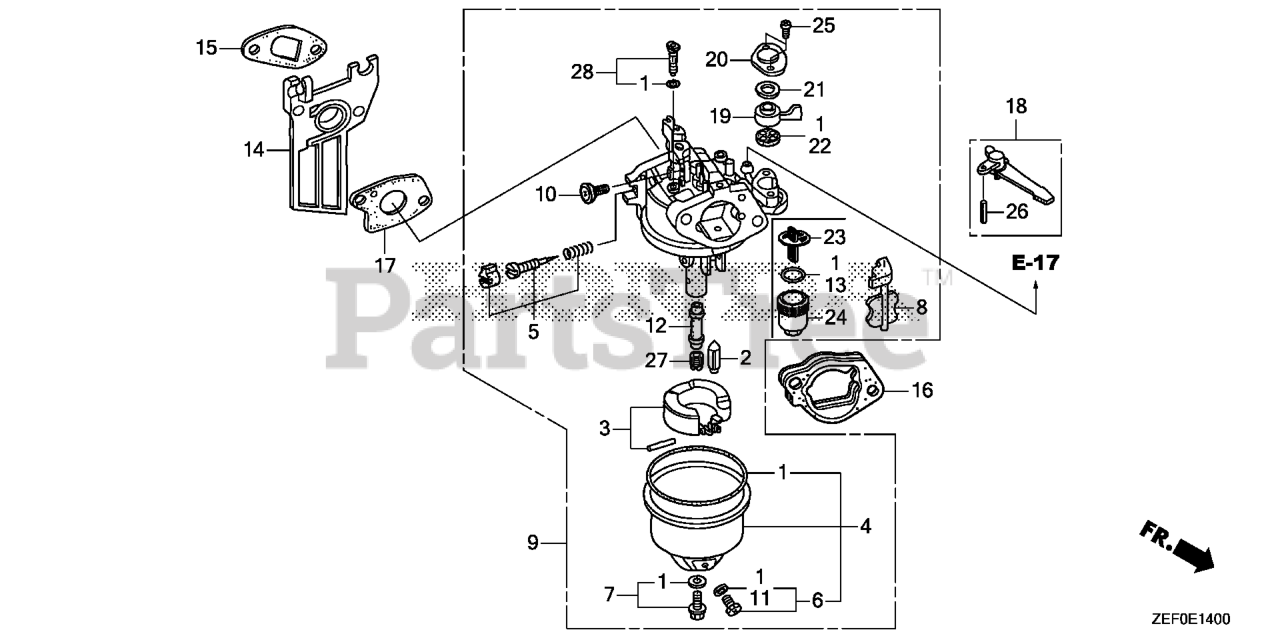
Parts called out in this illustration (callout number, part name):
1	GASKET SET
2	VALVE SET, FLOAT (CARBURETOR NO.) (SEAT NOT INCLUDED)
3	FLOAT SET
4	CHAMBER SET, FLOAT
5	SCREW SET (CARBURETOR NO.)
6	SCREW SET, DRAIN
7	SCREW SET (CARBURETOR NO.)
8	CHOKE SET (CARBURETOR NO.)
9	CARBURETOR ASSY. (BE59Q C)
10	SCREW, THROTTLE STOP
11	WASHER, PLAIN (6.2X10.7 DRAIN) (CARBURETOR NO.)
12	NOZZLE, MAIN (CARBURETOR NO.)
13	GASKET, FUEL STRAINER CUP
14	INSULATOR, CARBURETOR
15	GASKET, INSULATOR
16	SPACER, CARBURETOR
17	GASKET, CARBURETOR
18	LEVER, CHOKE (STD)
19	LEVER, VALVE
20	PLATE, LEVER SETTING (CARBURETOR NO.)
21	SPRING, PETCOCK LEVER (CARBURETOR NO.)
22	GASKET, VALVE
23	FILTER, CUP (CARBURETOR NO.)
24	CUP, FUEL STRAINER
25	SCREW, PAN (3X6)
26	PIN, SPRING (2X12)
27	JET, MAIN (#72) (CARBURETOR NO.)
27	JET, MAIN (#75) (CARBURETOR NO.)
27	JET, MAIN (#70)
28	JET SET, PILOT (#38)
